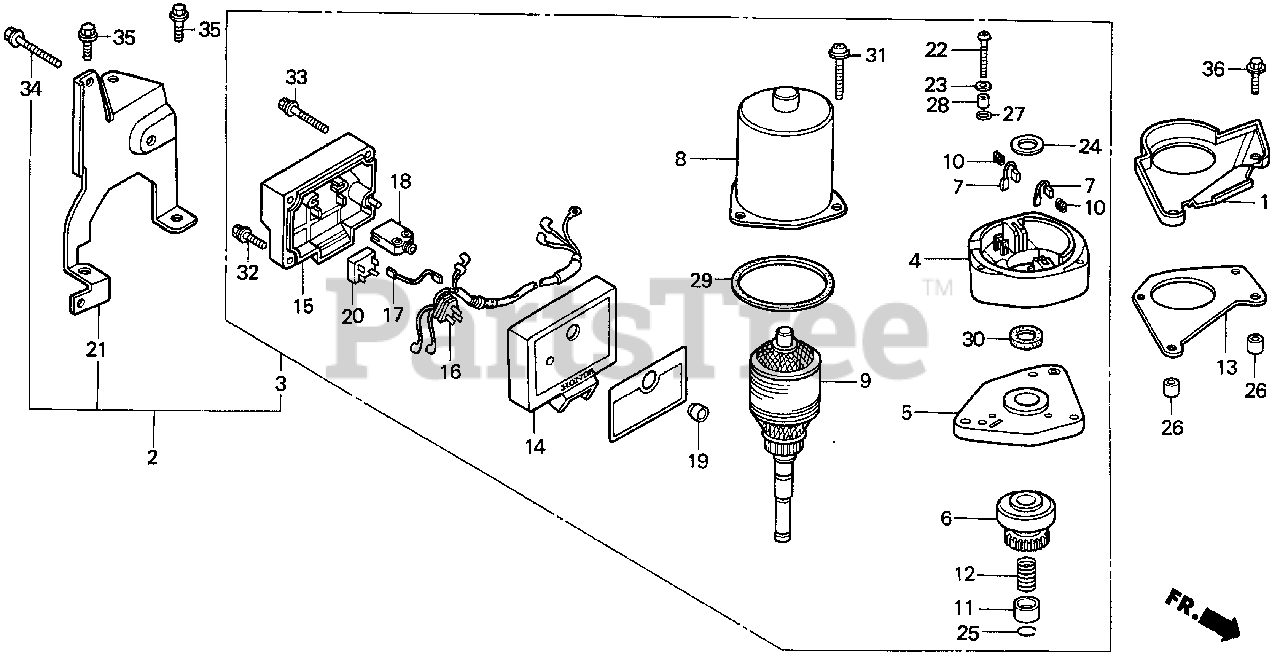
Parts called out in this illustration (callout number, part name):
1	PLATE, SIDE
2	MOTOR ASSY., STARTER (A.C.)
3	MOTOR ASSY., STARTER
4	HOUSING, CENTER
5	HOUSING, PINION
6	CLUTCH
7	BRUSH
8	YOKE
9	ARMATURE
10	SPRING, BRUSH RETURN
11	STOPPER, PINION
12	SPRING, COIL
13	BRACKET, STARTER MOTOR
14	COVER
15	CASE
16	WIRE
17	SUB-WIRE
18	SWITCH, STARTER (A.C. 380V-16A)
18	SWITCH, STARTER (A.C. 250V-16A)
19	CAP
20	DIODE
21	BRACKET, SWITCH BOX
22	SCREW, TRUSS (4X30)
23	WASHER, STAR (4MM)
24	WASHER B
25	RING, RETAINING
26	PIN A, DOWEL (10X14)
27	O-RING
28	COLLAR
29	GASKET
30	OIL SEAL
31	SCREW-WASHER (5X40)
32	SCREW-WASHER (4X20)
33	SCREW-WASHER (4X30)
34	BOLT, FLANGE (6X40)
35	BOLT, FLANGE (8X25)
36	BOLT, FLANGE (8X28)
